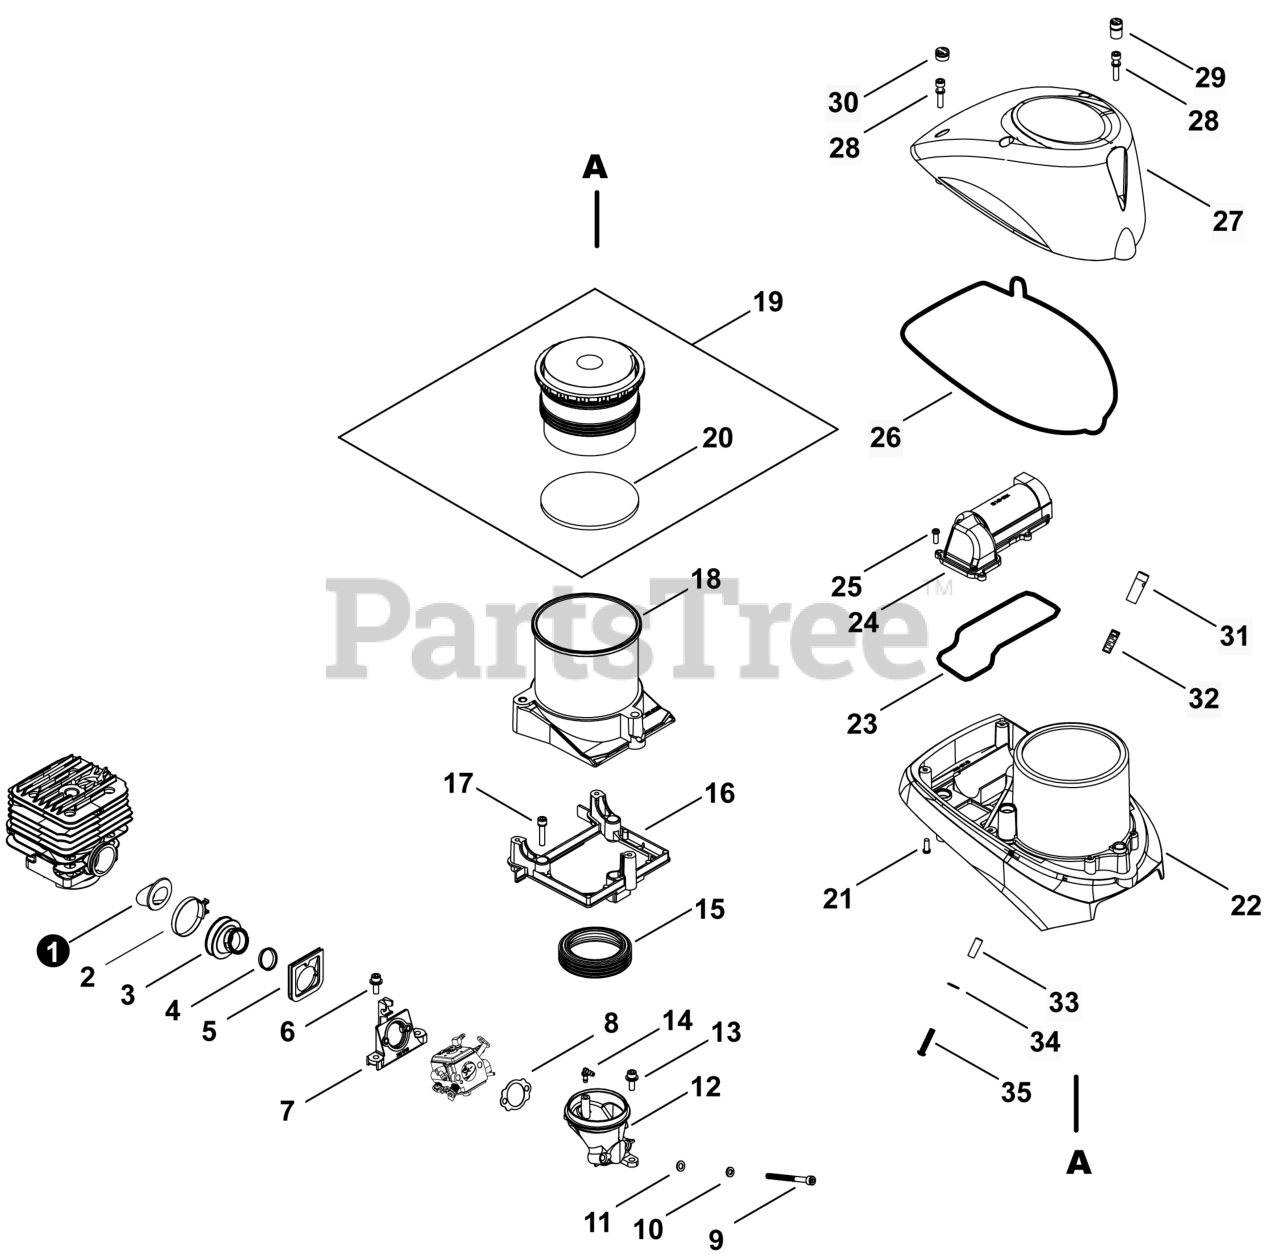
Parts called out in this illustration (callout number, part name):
1	PIPE, INTAKE
3	BELLOWS, INTAKE
4	SLEEVE 18
7	INSULATOR, INTAKE
8	GASKET, INTAKE
9	BOLT 5×60
10	WASHER, SPRING 5
11	WASHER, FLAT 5.5×10×0.8
12	ELBOW, CARBURETOR
14	CONNECTOR, PIPE
16	SUPPORT, FILTER
17	BOLT M5×25
18	CASE ASSY, AIR FILTER
19	AIR FILTER KIT
20	FILTER, DISK
21	SCREW 4
21	SHAFT, DECOMPRESSSION
22	COVER, AIR FILTER
23	SEAL, CLEANER
24	COVER, AIR FILTER
25	SCREW 4
26	SEAL, CLEANER
27	COVER, CYLINDER
29	GROMMET, PLUG
30	GROMMET, PLUG
32	SPRING, COMPRESSION
34	WASHER 5.5×12×0.8
35	SCREW 5
